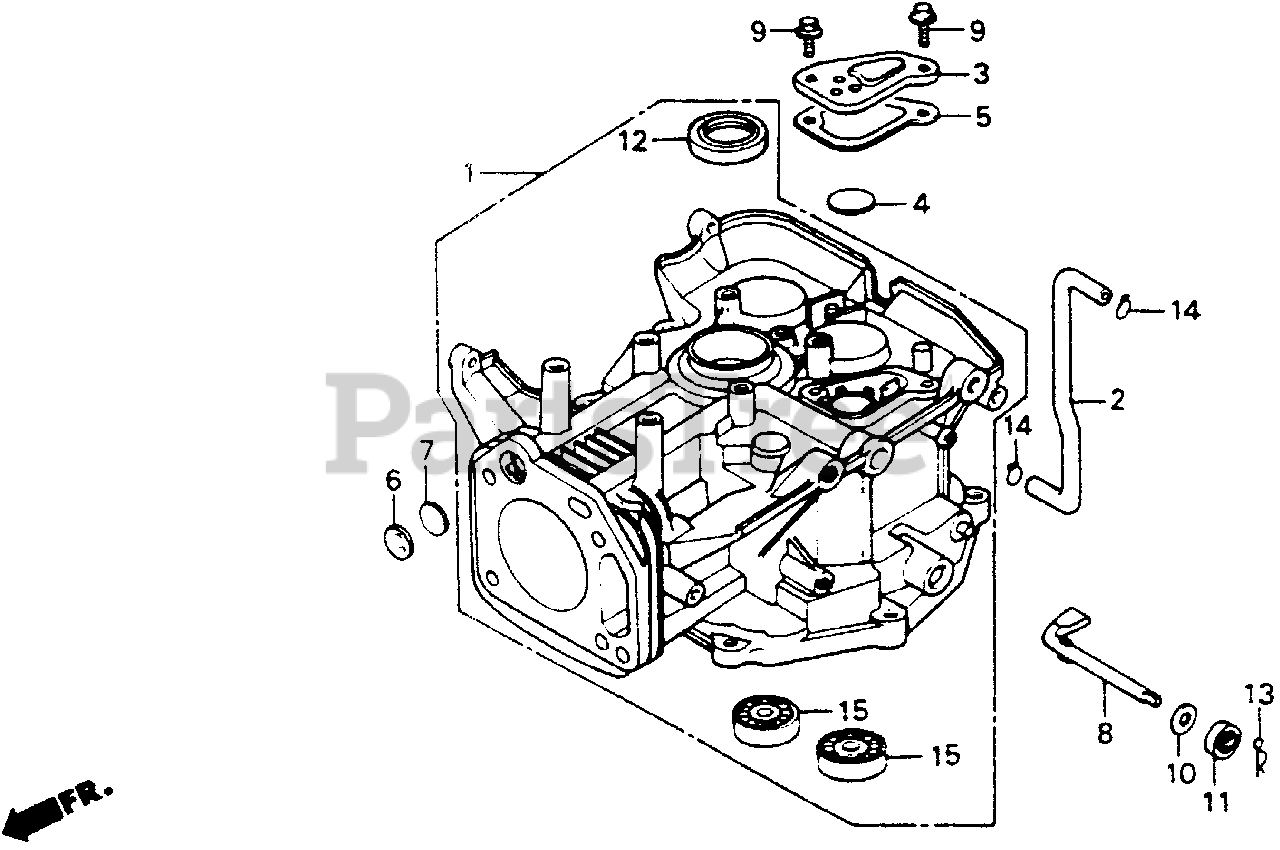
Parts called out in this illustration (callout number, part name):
1	CYLINDER ASSY.
2	TUBE, BREATHER
3	CAP, BREATHER CHAMBER
4	VALVE, BREATHER
5	GASKET, BREATHER CAP
6	PLATE, ONE-WAY VALVE
7	VALVE, ONE-WAY
8	SHAFT, GOVERNOR ARM
9	BOLT, FLANGE (6X12) (CT200)
10	WASHER, THRUST (8.1MM)
11	OIL SEAL (8X14X5)
12	OIL SEAL (35X52X8)
13	PIN, LOCK (8MM)
14	CLIP, TUBE (C11)
15	BEARING, RADIAL BALL (6202)
